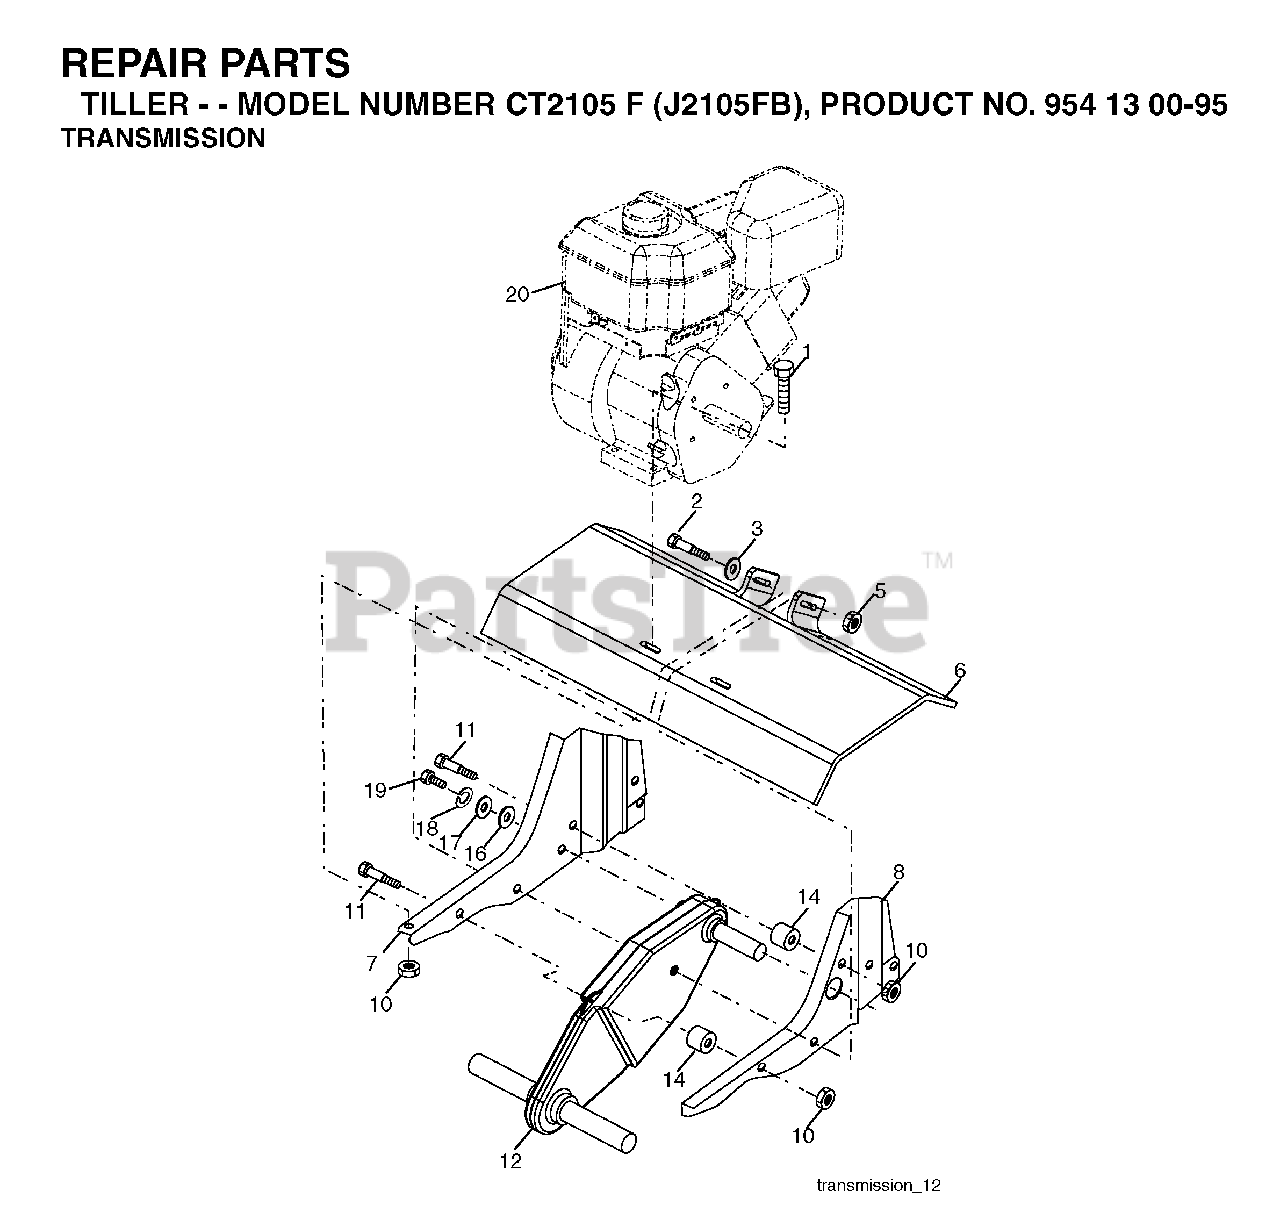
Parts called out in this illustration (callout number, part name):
1	BOLT
3	WASHER
5	NUT LOCK FLG 3/8-16 UNC
7	RP BRACKET, ENGINE, R.H.
8	BRKT.ENGINE.LH.BLACK
10	LOCKNUT-FLANGE 5/16-18
11	BOLT, HEX HEAD 5/16-18 X 2.5
18	LOCKWASHER
